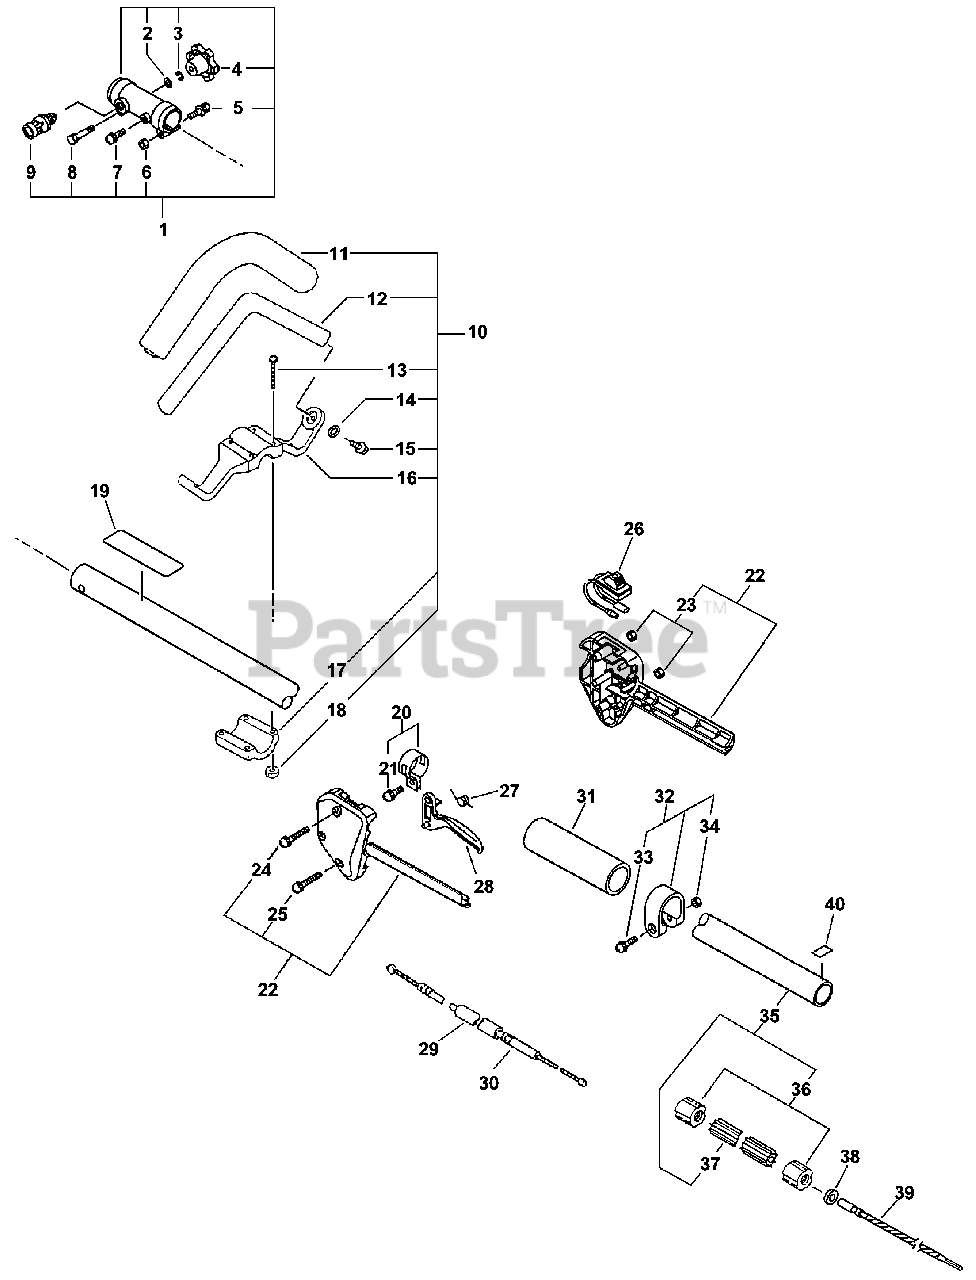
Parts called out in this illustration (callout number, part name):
1	COUPLER ASSY
2	WASHER - 5
3	LOCKWASHER - 5
4	THUMBSCREW
5	SCREW - 5X30
7	SCREW - 5X12
8	SCREW - 5X40
9	LATCH ASSY
10	HANDLE ASSY - FRONT
11	GRIP, HANDLE
12	HANDLE - FRONT
13	SCREW - 5X40
14	WASHER - 5
15	SCREW - 5X20
16	BRACKET, HANDLE - UPPER
17	BRACKET, HANDLE - LOWER
19	LABEL - CAUTION -- SPANISH
20	CLAMP KIT
21	SCREW - 5X14
22	CONTROL HANDLE KIT
24	SCREW - 5X35
25	SCREW - 5X25
26	IGNITION SWITCH ASSY
27	SPRING, TRIGGER
28	TRIGGER, THROTTLE
29	TUBE, PROTECTIVE - CORRUGATED
30	CABLE, THROTTLE
31	GRIP, HANDLE
32	CLAMP KIT
33	SCREW - 5X28
35	MAIN PIPE ASSY
37	LINER - FLEXIBLE
39	DRIVESHAFT - FLEXIBLE -- UPPER
40	LABEL - ALIGNMENT
